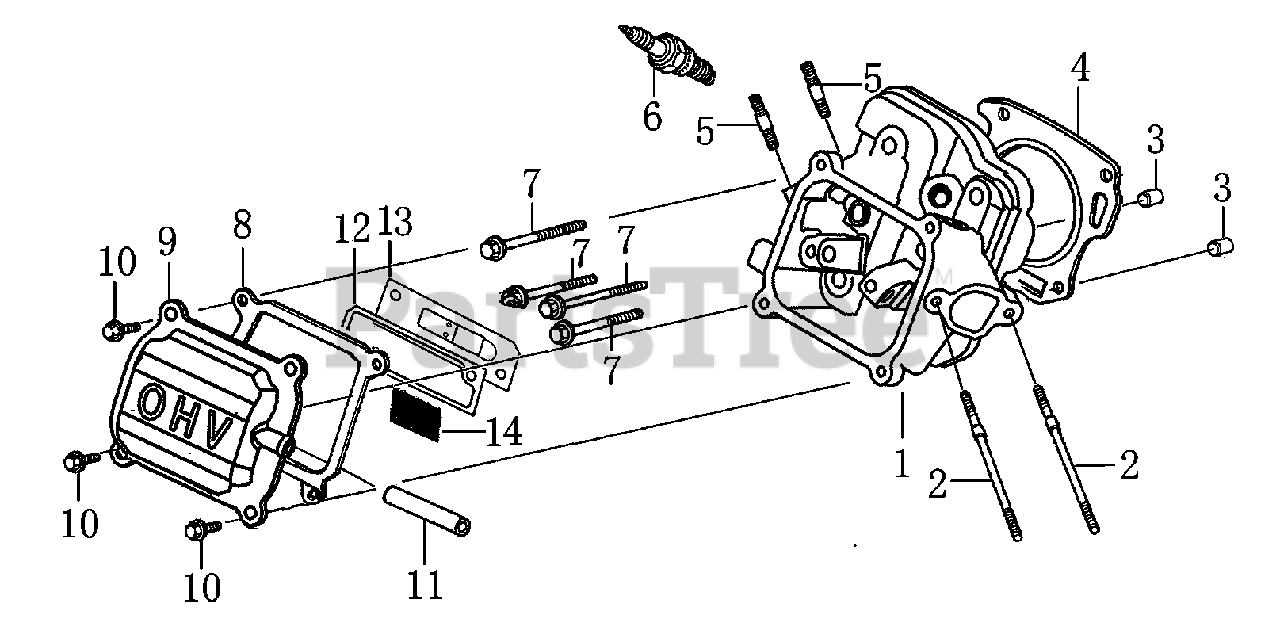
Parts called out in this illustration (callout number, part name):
1	HEAD, CYLINDER
2	BOLT, STUD, IN.
3	PIN, DOWEL
4	GASKET, CYLINDER HEAD
5	BOLT, STUD , EX.
6	PLUG, SPARK
7	BOLT, HEAD, FLANGED
8	GASKET, VALVE COVER
9	COVER, VALVE
10	BOLT, FLANGE
11	TUBE, BREATHER
12	GASKET, BREATHER CHAMBER
13	CAP, BREATHER CHAMBER
14	STRAINER, OIL
